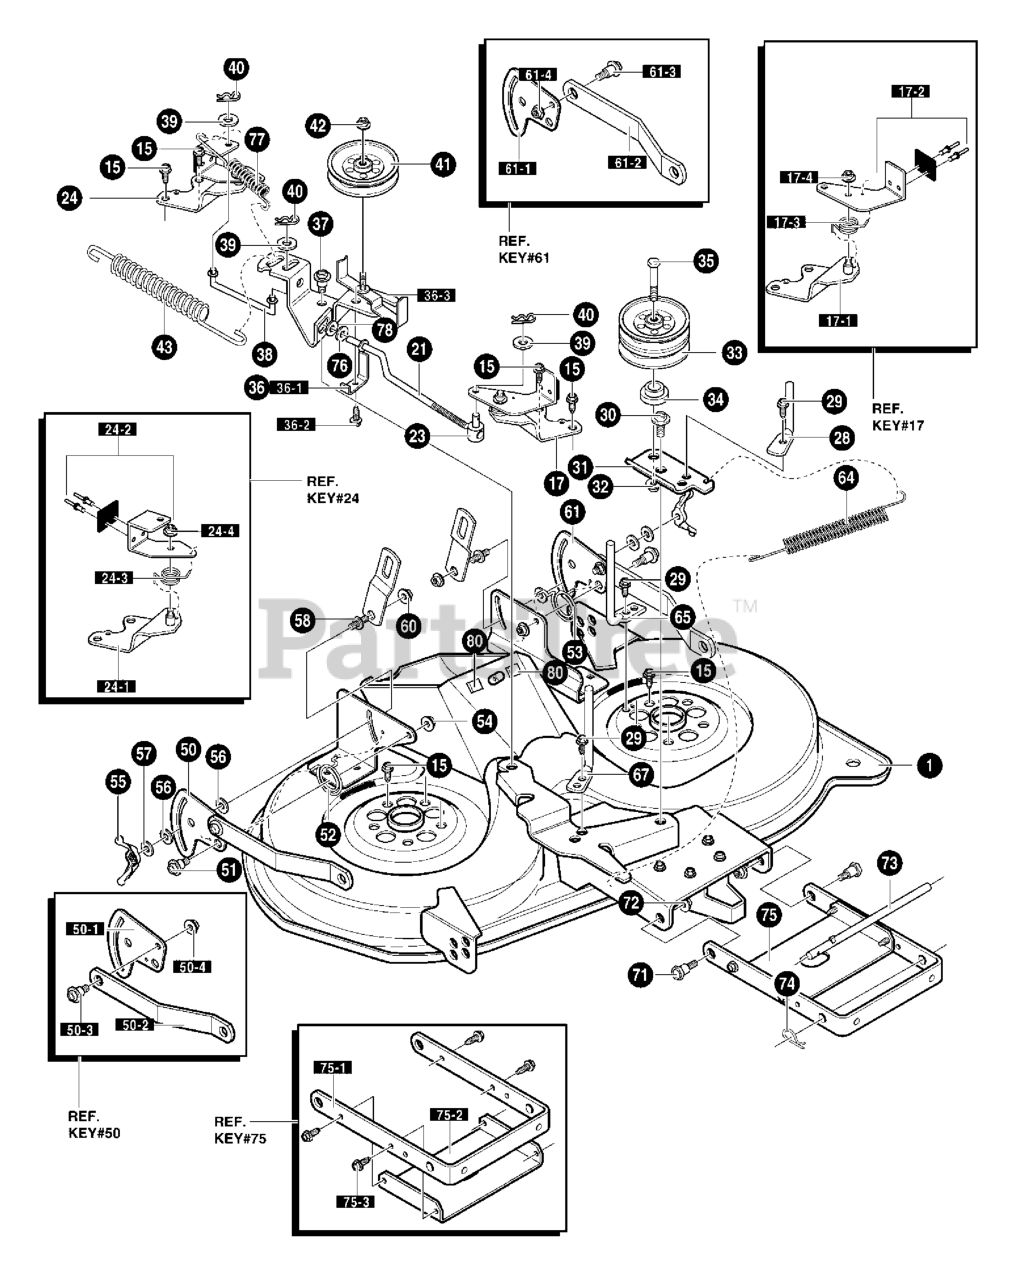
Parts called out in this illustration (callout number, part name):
1	MOWER DECK REBA
15	SCREW, 3/8-16 x 1.00 WAHHSPTAP
17	BRAKE ARM ASSEMBLY LH
17-1	BRAKE SUPPORT ASSEMBLY LH
17-2	BRAKE ARM ASSEMBLY LH
17-3	SPRING, TORSION
17-4	NUT, 5/16-18 WDFLLK
21	LINK, BRAKE LH
23	NUT, ADJUSTING
24	BRAKE ARM ASSEMBLY RH
24-1	BRAKE SUPPORT ASSEMBLY RH
24-2	BRAKE ARM ASSEMBLY RH
24-3	SPRING, TORSION .75IX.50X.166
24-4	NUT, 5/16-18 WDFLLK
28	BELT GUIDE
29	SCREW, 5/16-18 x 0.50
30	BOLT, .50X.75 HHSH 3/8-16
31	ARM, DOUBLE IDLER
32	NUT, 3/8-16 HWDFLLK MACK
33	PULLEY, IDLER DOUBLE VEE
34	SPACER, DECK
35	Screw, 3/8-16 x 3.00
36	IDLER ARM ASSY
36-1	SPRING - BELT GUIDE
36-2	SCREW 1/4-20X.50 WAHHTAP
36-3	IDLER ARM ASSEMBLY
37	BOLT, .50X.75 HHSH 3/8-16
38	LINK, BRAKE RH
39	WASHER, FLAT
40	PIN, HAIR .38 DIA.X1.64LG
41	PULLEY, V IDLER 4"
42	NUT, 3/8-16HWDFLLK MACK
43	SPRING, EXTN 5.40X.714OD
50	ASM. PLATE, REAR SUS. BRKT, RH
50-1	PLATE-SUSPENSION
50-2	SUSPENSION BRKT REAR
50-3	BOLT, SHOULDER 3/8-16
50-4	NUT, 3/8-16 HWDFLLK MACK
51	BOLT, SHOULDER .375
52	SPRING, TORSION .68LG RH
53	SPRING, TORSION .68LG LH
54	NUT, 3/8-16 HWDFLLK MACK
55	WINGNUT, 5/16-18 YZ
56	PAD, FRICTION
57	WASHER
58	PIN, HANGER
60	NUT, 3/8-16 HWDFLLK MACK
61	ASM. PLATE, REAR SUS. BRKT LH
61-1	PLATE - SUSPENSION
61-2	SUSPENSION BRKT REAR
61-3	BOLT, SHOULDER 3/8-16
61-4	NUT, 3/8-16 HWDFLLK MACK
64	SPRING, EXTN 4.20X.750D
65	GUIDE, BELT
67	GUIDE, BELT
71	BOLT, SHOULDER .375
72	NUT, 3/8-16 HWDFLLK MACK
73	ZINC ROD, HANGER
74	PIN, HAIR
75	SUB. ASM. BRKT & STIFFNER
75-1	BRACKET, FRONT SUSPENSION
75-2	STIFFENER, DECK
75-3	SCREW, 5/16-18 x 0.75 HHWATAP
76	WASHER, FLAT
77	SPRING, EXTENSION 1.94LG
78	WASHER, FLAT INSULATE
80	PAD, ADHESIVE 1.00X1.50X.12
